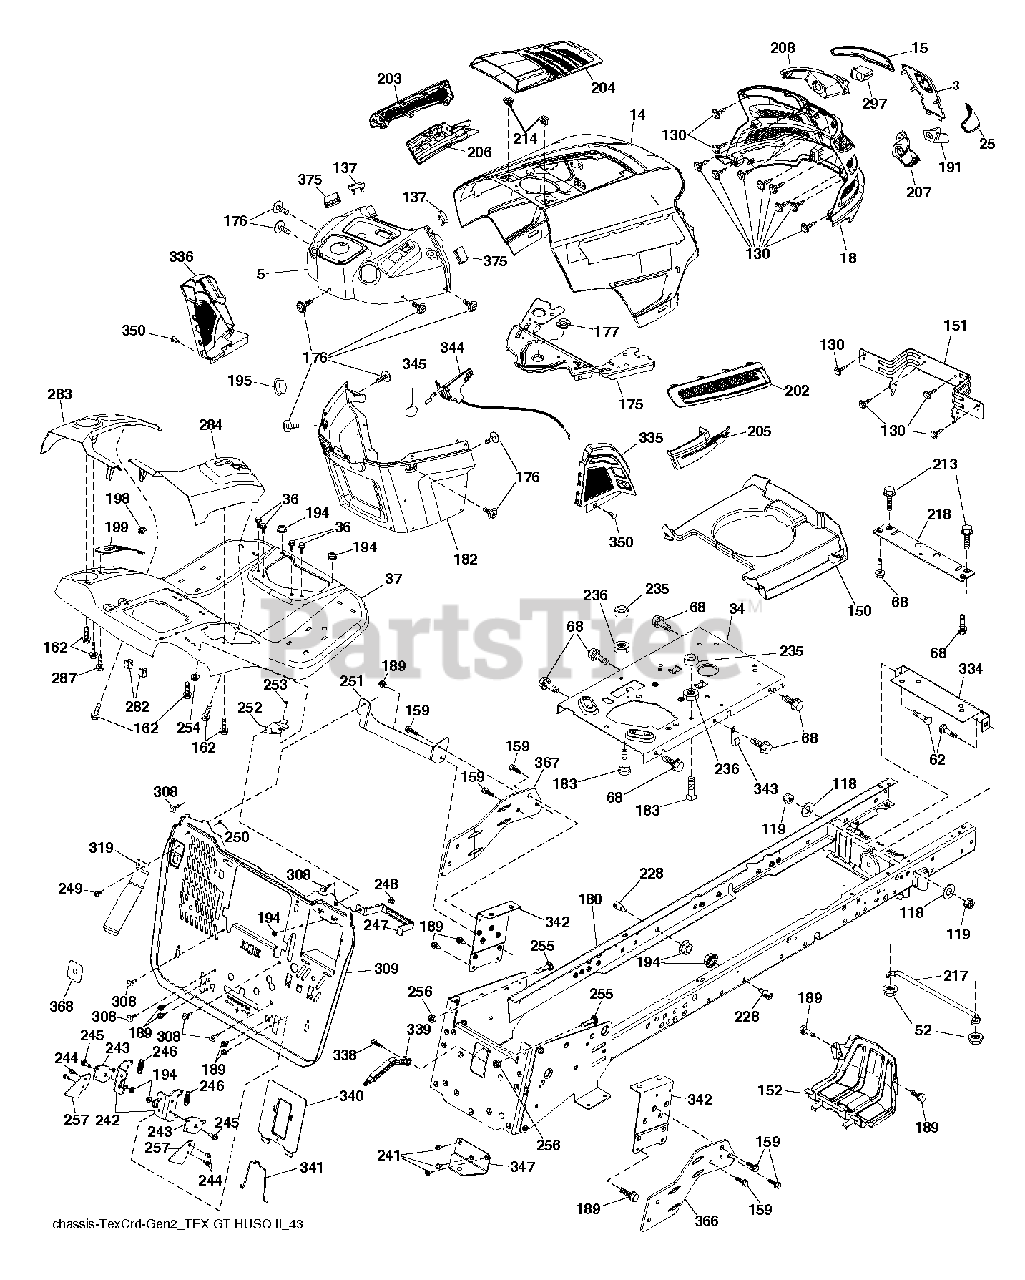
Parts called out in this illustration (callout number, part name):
3	APPLIQUE.SUBASM.GT.HUSQ.II
5	UPPER.GT2.SVC.MINDING.PTO.H.
14	HOOD.ASM.HUSQVARNA.GT.TEX.ORAN
15	LENS.HEADLIGHT.LH.GTII.2011
18	GRILLE.SUBSTRATE.2011.
25	LENS.HEADLIGHT.RH.GTII.2011
34	PLATE.ENGINE.10GA.CRD.GENII
36	SCREW 5/16"
37	FENDER.TEX.SRD.CRD.BASE
52	LOCKNUT
62	BOLT D
68	SCREW LT
118	WASHER
130	SCREW.#10 X 0.750.BOS
137	BUMPER DASH
150	AIR.DUCT.GTV.BLACK
151	BRACKET.PIVOT.HOOD.GT.HUSQ.II
152	SHIELD.BROWNING.PNT.GT.V2
159	SCREW, 3/8-16X3/4
162	SCREW.HI-LO.CONSOLE
175	PLATE.CROSSMEMBER.HUSQ
176	SCREW.#10-24X5/8.RN.QU
177	BUSHING STEERING
180	WELDMENT.CHASSIS.TEX.CRD.GEN.2
182	DASH DASH LOWER
183	BOLT.5/16-18X1-1/4 FULL THD
189	SCREW
191	INSERT.REFLECTIVE.RH.HUSQ.GTII
194	NUT LOCK HEX FLANGE 5/16-18
195	PLUG.HOLE.DASH.LOWER.12V.BLK
198	INDICATOR.DECK.LIFT.RED
199	PLATE DECK LIFT
202	VENT.SIDE.RH.GT.HUSQ.II.
203	VENT.SIDE.LH.GT.HUSQ.II.498
204	VENT.TOP.HUSQ.GT2
205	SIDE.TRIM.RH.GT.HUSQ.II
206	SIDE.TRIM.LH.GT.HUSQ.II.GRAY
207	BEZEL LIGHT.RH.GT.II.MYLAR
208	BEZEL LIGHT.LH.GT.II.MYLAR
213	BOLT
214	CLIP.RETAINER.TINNER.
217	ROD.PIVOT.HOOD
218	X-PIECE.HOOD.STOP.NON/
228	STUD.FASTNER.W/ANTI-ROTATE
235	SPACER FENDER
236	NUT.CENTERLOCK.5/16-
241	SCREW 5/16-18X1
242	LATCH.BRACKET.TCRD.GEN 2.5.BAG
243	ARM.PIVOTING.TCRD.GEN2.5.BAGGE
244	SCREW
245	BOLT, SHOULDER
246	SPRING.TCRD.GEN2.5.BAGGER.EXT
247	STRAP.BATTERY.TCRD.GE
248	BOLT
249	SCREW.BUTTONHD.10-24X1/2.(2 2)
250	NUT 10-24 NYLOC
251	BRKT.TOPSPPRT.BCKPLT.
252	BRKT.TOPSPPRT.BCKPLT.RH.CRD2.5
253	BOLT
254	NUT T
255	BOLT.CROSSDRILLED.381
256	Hex Nut, 3/8-16
257	LATCH.BAGGER.TEXCRD2.5
282	CLIP.RETAINER.CONSOLE.LT.HUSQ
283	CONSOLE.DECKLIFT.CRDII.498
284	CONSOLE.PEDAL.HYDRO
287	SCREW 1/4X20
297	INSERT.REFLECTIVE.LH.HUSQ.GTII
308	BOLT, 5/16-18 X 1 3/4
309	BACKPLATE.TEXCRD2.5.B
319	LEVER.BAG.CRDII.ANTIROTATION
334	BRACKET.ENGINE
335	COVER.LOWER.DASH.RH.BLACK
336	COVER-LH.LOWER.DASH.GT2.BLACK
338	BOLT BOLT SHOULDER
339	LEVER LEVER BAGGER
340	BATTERY.DOOR.TCRD.GEN
341	LATCH.BATTERY.DOOR.TC
342	SUPPORT SUPPORT FENDER
343	CLIP CLIP
344	CONTROL.EZ.MULCH.TEX/CRD
345	RP KNOB.OVAL.TAPERED.3/8-16BLK
347	HITCH HITCH TOW TEX CRD GEN 2
350	CLIP.X-MAS.TREE
366	BRACKET.RH.FRONT.BAGGER.BLACK
367	BRACKET.LH.FRONT.BAGGER.BLACK
368	FULL.LEVER.BAGGER.TEX.CRD
375	BUMPER CLIP-ON. DASH 1"
